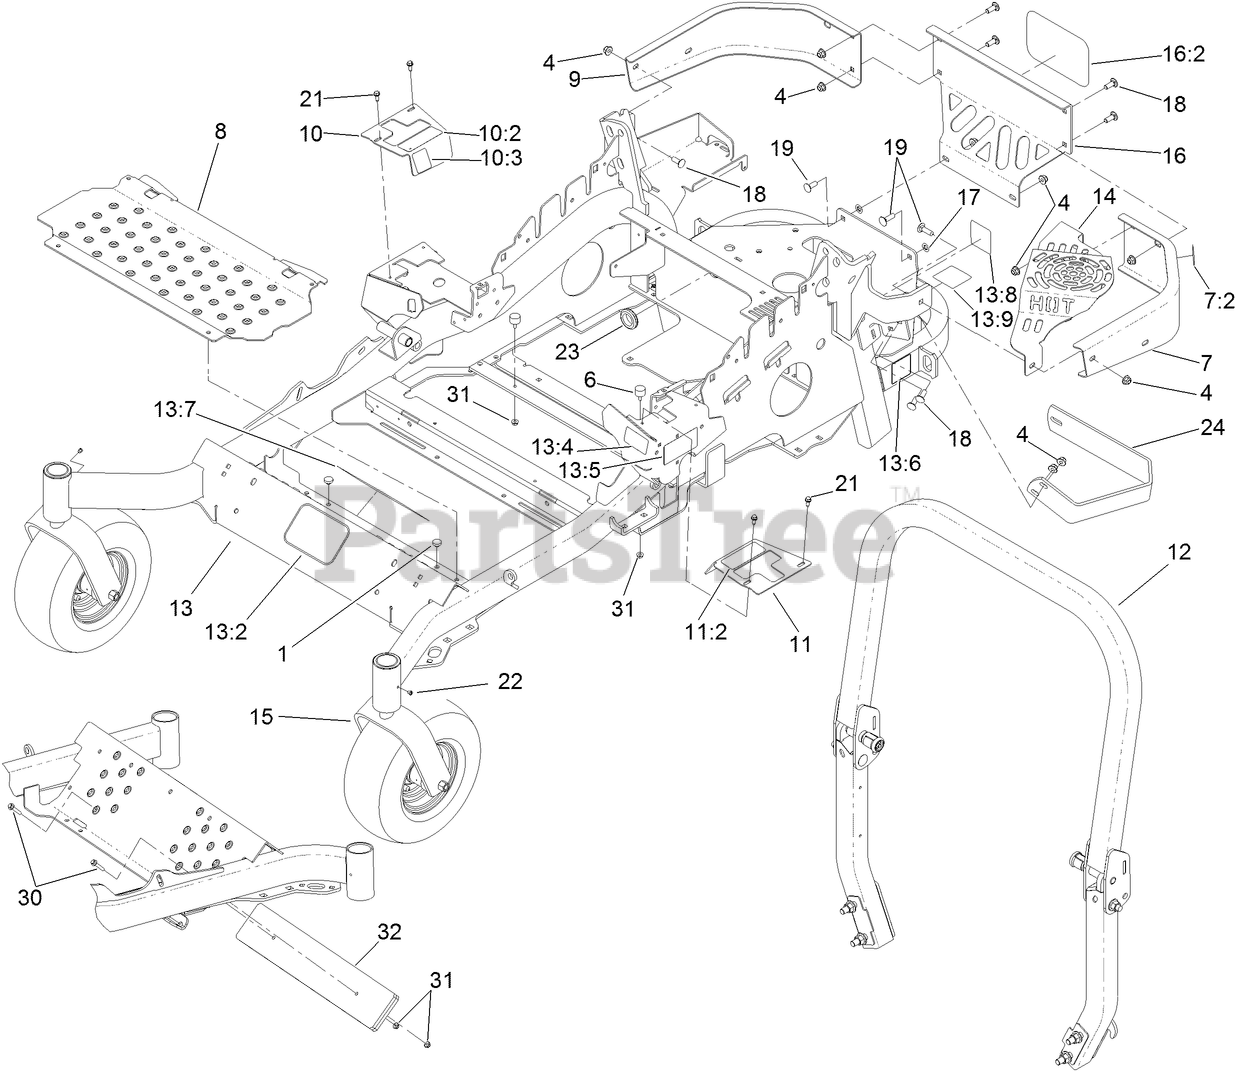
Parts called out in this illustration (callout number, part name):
1	BUMPER
4	NUT-HF, NI
6	BUMPER-RUBBER (W/ STUD)
7	BUMPER-REAR, LH
7:2	DECAL-CAUTION
8	FLOORPAN
9	BUMPER-REAR, RH
10	COVER ASM-MOTION CONTROL
10:2	DECAL-MOTION CONTROL
10:3	DECAL-PARK BRAKE
11	COVER ASM-MOTION CONTROL
11:2	DECAL-MOTION CONTROL
12	ROPS ASM
13	FRAME ASM
13:2	DECAL
13:4	DECAL-FUEL FILL
13:6	DECAL-BELT DRIVE
13:7	DECAL-SLOPE
13:8	DECAL-SPARK ARRESTER
13:9	DECAL-BYPASS
14	GUARD-MUFFLER
15	FRONT CASTER ASM
16	REAR GUARD ASM
16:2	DECAL
17	NUT-PUSH
18	SCREW-CARR
19	BOLT-CARR
21	SCREW-HWH
23	GROMMET
24	GUARD-MUFFLER, SIDE
30	SCREW-HHF
31	NUT-HF
